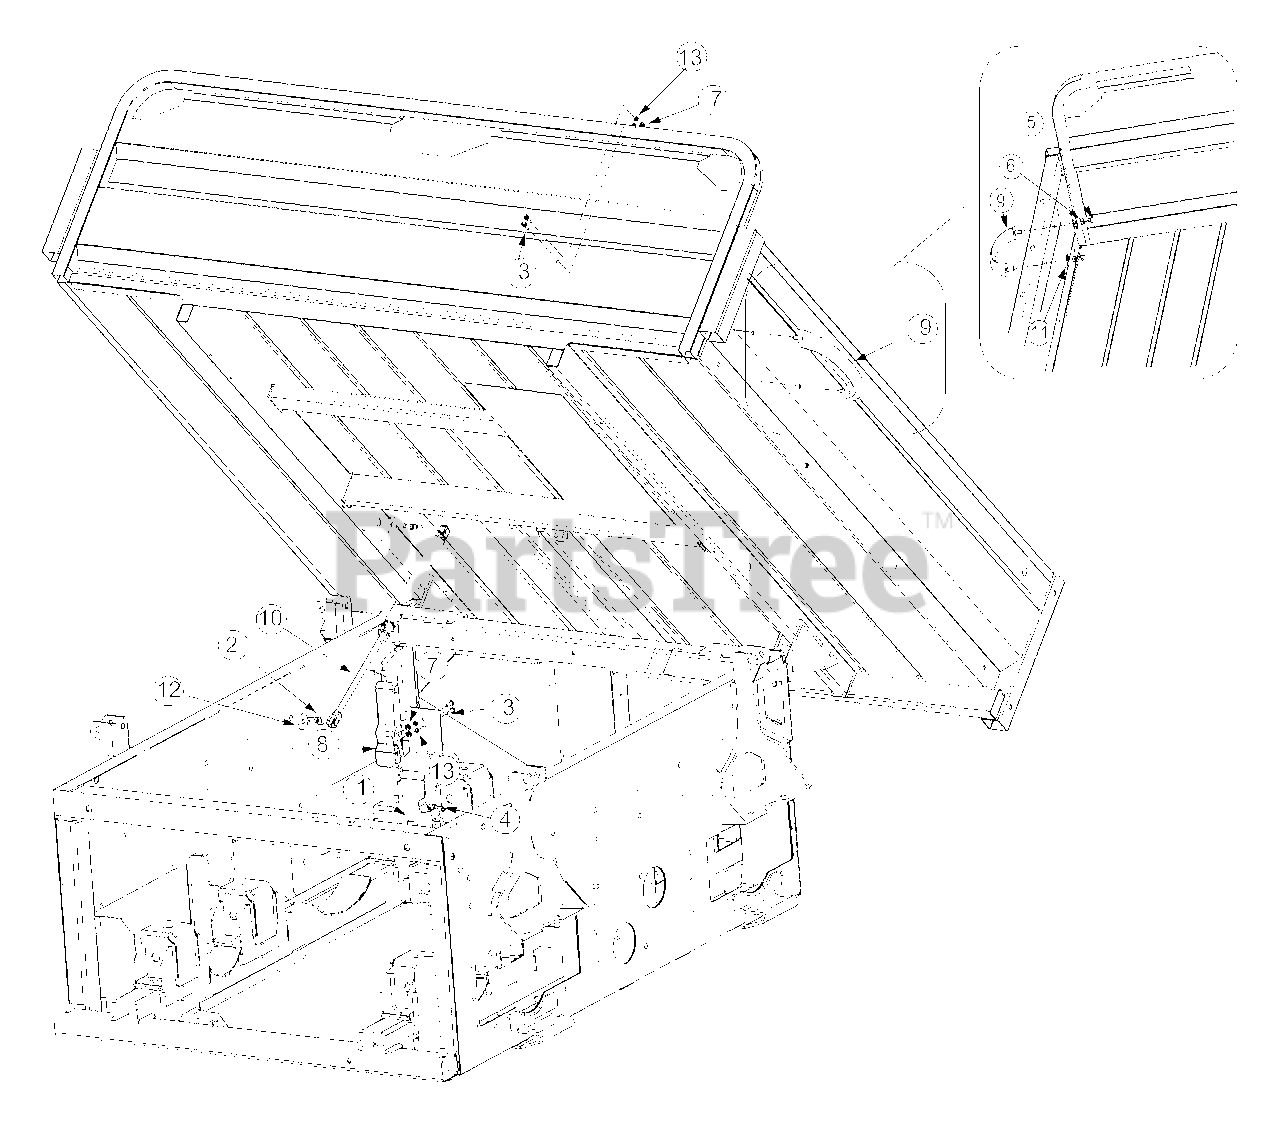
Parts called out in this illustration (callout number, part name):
1	Bracket, Bed Latch Base
2	Stud, Ball 5/16-18
3	Screw, Hex Sems, #10-32 x .62, Gr5
4	Hex Screw, 5/16-18 x .625, Gr5
5	Nut, Acorn 1/4-20 w/o Lock
6	Nut, Hexlock, 1/4-20
7	Hex Nut, 10-32
9	Handle, Bag w/Screw
10	Spring, Gas .91 Stroke
11	Washer, Flat .265 x .938 x .120
12	Washer, Flat .34 ID X1.125 OD x .12
13	Washer, Lock, #10
